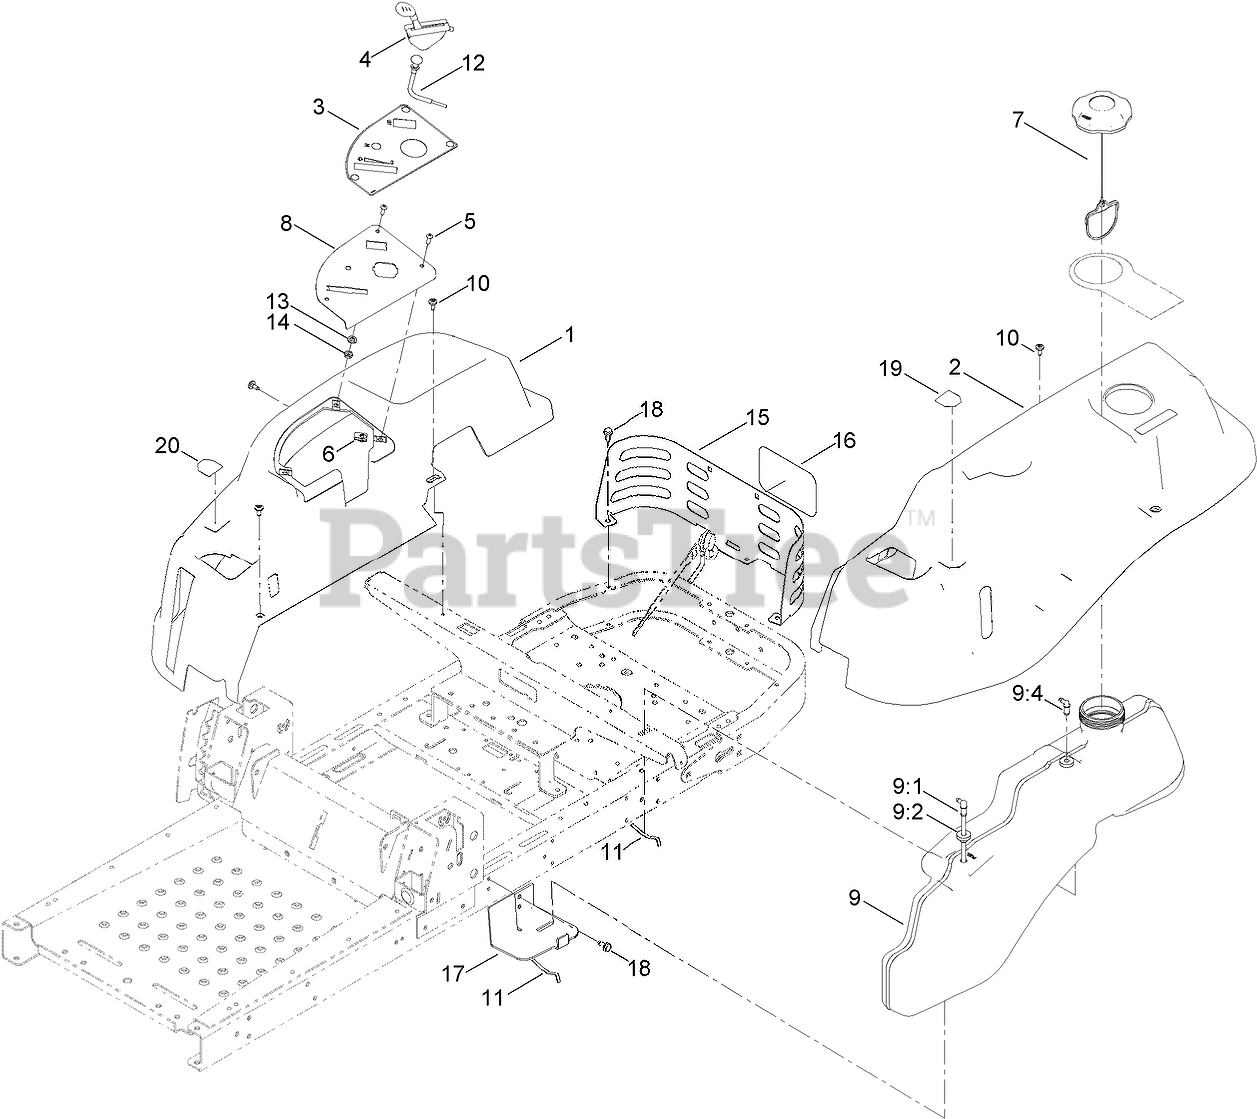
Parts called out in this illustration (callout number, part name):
1	POD-RH
2	POD-LH
3	DECAL-PANEL, CONTROL
4	CABLE-THROTTLE
5	SCREW-PRH
7	CAP-FUEL, RATCHETING
8	PLATE-CONTROL
9	FUEL TANK ASM
9:1	CONNECTOR-ELBOW, 90 DEG
9:2	BUSHING
9:4	FITTING-PLASTIC
10	SCREW-SHOULDER
11	SPRING
12	CABLE-CHOKE
13	WASHER-LOCK
14	NUT-HJ
15	GUARD-REAR
16	DECAL
17	SUPPORT-TANK, FRONT
18	SCREW-HWHTF
19	DECAL-CONTROL LEVER, LH
20	DECAL-CONTROL LEVER, RH
